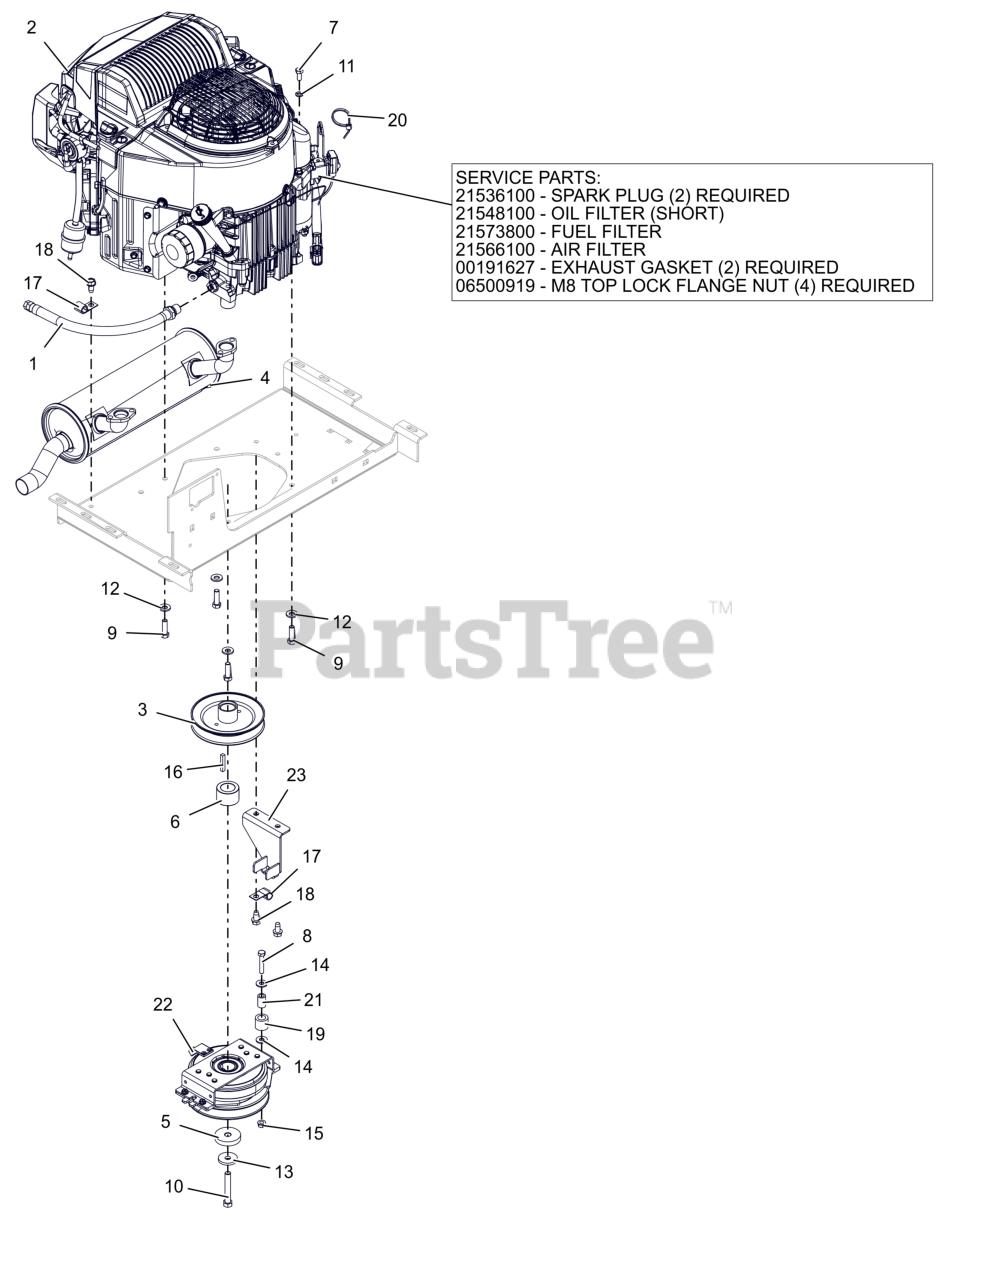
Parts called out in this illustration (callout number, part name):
1	HOSE, OIL DRAIN
2	ENGINE, KAWASAKI FT730
2	PLUG, SPARK
2	OIL FILTER, KAWASAKI FR
2	FUEL FILTER
2	AIR FILTER, KAWASAKI
2	GASKET, MUFFLER S/O
2	NUT-LK-TOP-FLG M8 ZCC
3	WLDMT, TRANSAXLE DRIVE PULLEY
4	MUFFLER, KAW FX691/730
5	SPACER, .450X2.00X.396
6	SPCR, 1.125 x 1.750 x 1.147
7	BLT, HEX M8-1.25X20 G8.8 ZCC
8	BLT, HEX .31-18X1.75 G5 ZCC
9	BLT, HEX .38-16X1.25 G5 ZCC NT
10	BLT, HEX 0.4375-20X2.75 G8 ZCC NT
11	WSHR,LK-REG .312X.078 ZCC
12	WASHER, 3/8" SPRING DISC
13	WASHER, 7/16" SPRING DISK
14	WSHR,FLT .375X.875X.083 ZCC
15	NUT,LK-CTR-FLG .31-18 GF ZCC
16	KEY-SQ .25 X 1.50 X .25 SAE
18	SCR,TAP .375-16X.75 HWH TR ZCC
19	BUMPER,RUBBER .62X1.0X.88 LG
20	CABLE TIE LG 5-1/2
21	BUSH.,S.391X.622X.950 ST
22	CLUTCH- OGURA GT2.75-DC03(D)
23	BRKT- CLUTCH STOP - BLACK
